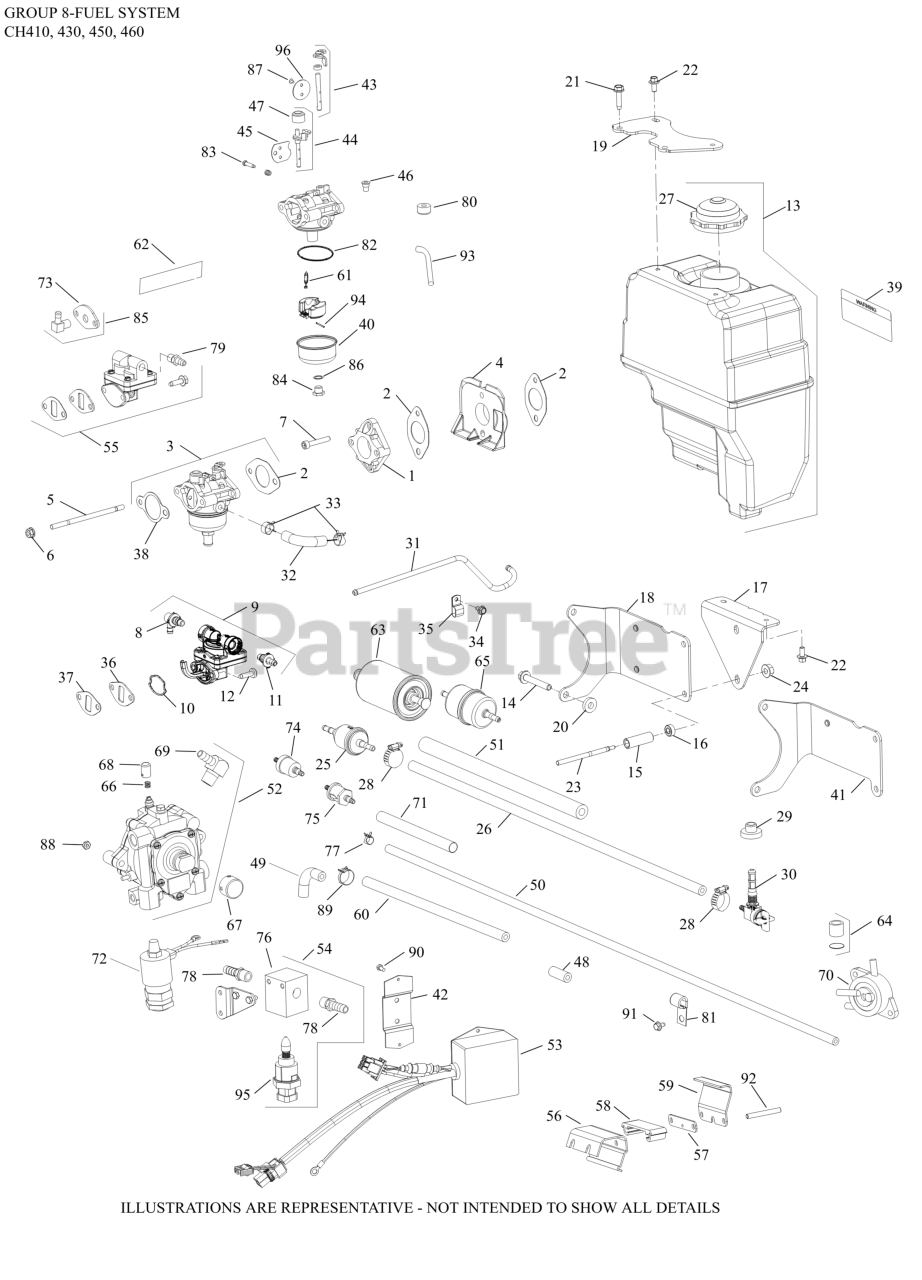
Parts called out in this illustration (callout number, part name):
1	ADAPTER, CARBURETOR-(#DSC)
2	GASKET, CARBURETOR
3	KIT, CARBURETOR WITH GASKETS
4	DEFLECTOR, HEAT
5	STUD,M6X1.0X116
6	NUT, FLG M6X1.0
7	SCREW, SKT CAP M6X1.0X35
8	CONNECTOR, 90 DEG. HOSE
9	KIT, FUEL PUMP
10	O-RING, FUEL PUMP
11	KIT, STRAIGHT FITTING
12	SCREW, LBD SKT M6x1.0x20-(#25086403S)
13	KIT, FUEL TANK
14	SCREW, FLG M8X1.25X50
18	BRACKET, FUEL TANK
19	BRACKET, FUEL TANK
20	WASHER, FLAT 11/32"
21	SCREW,FLG THD FRM M6X1.0X25-(#25086395S)
22	SCREW, FLG M6X1.0X12
23	STUD, M8X1.25X133-USE 25 755 54-S
24	NUT, FLG M8X1.25
25	FILTER,FUEL 51 MICRON (FUEL PUMP)
26	HOSE,LW PERM.FUEL 24.00"-USE 25 111 81-S
27	CAP, FUEL TANK
28	CLAMP, HOSE (KM)-USE 25 237 31-S
28	CLAMP, HOSE
28	HOSE CLAMP USE 25 237 14-S
29	BUSHING, FUEL TANK
30	VALVE, FUEL SHUT-OFF
31	LINE, FUEL-DISCONTINUED
32	HOSE, FUEL LOW-PERMEATION
33	CLAMP, BAND SPRING HOSE-(#2523737S)
34	SCREW, FLG THD FRM M5X.8X10
39	DECAL, FUEL TANK-DISCONTINUED
NI	KIT, HIGH ALTITUDE (+10,000 FT)
NI	KIT, REPAIR FLOAT
NI	KIT, REPAIR CARB (PUMP FEED)
NI	KIT, CHOKE REPAIR
NI	KIT, REPAIR BOWL REPLACEMENT
NI	KIT, HIGH ALTITUDE (5-10,000 FT)
